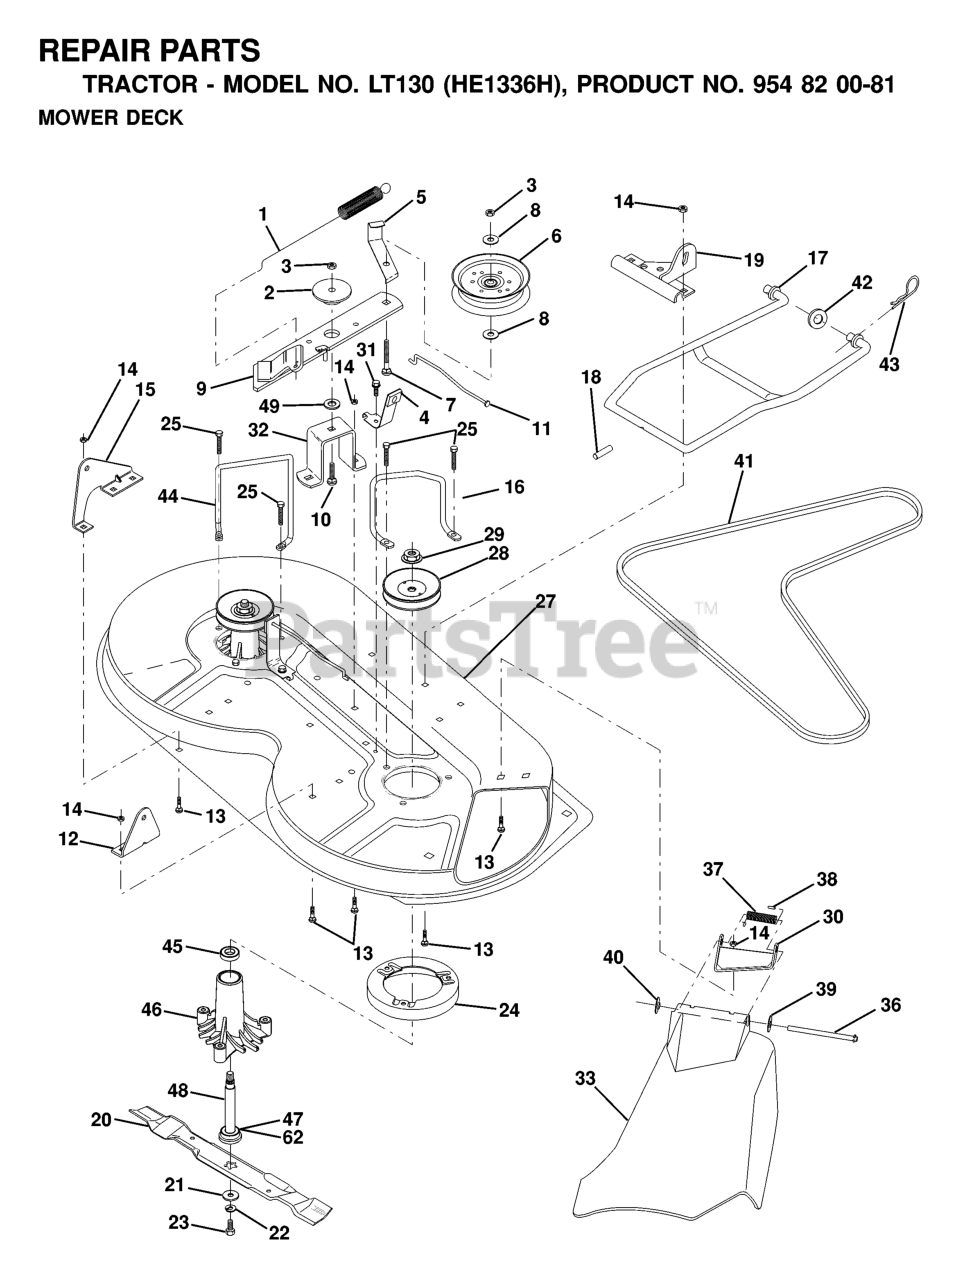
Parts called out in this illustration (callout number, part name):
12	HYDROSTAT 7A646024070
15	WASHER BRB 8.4X17
16	NUT
21	NUT
23	WASHER
26	LOCKNUT M5
33	TENSIONER
35	SCREW
37	LOCKNUT M8
38	WASHER
43	NUT
45	TANK CAP
